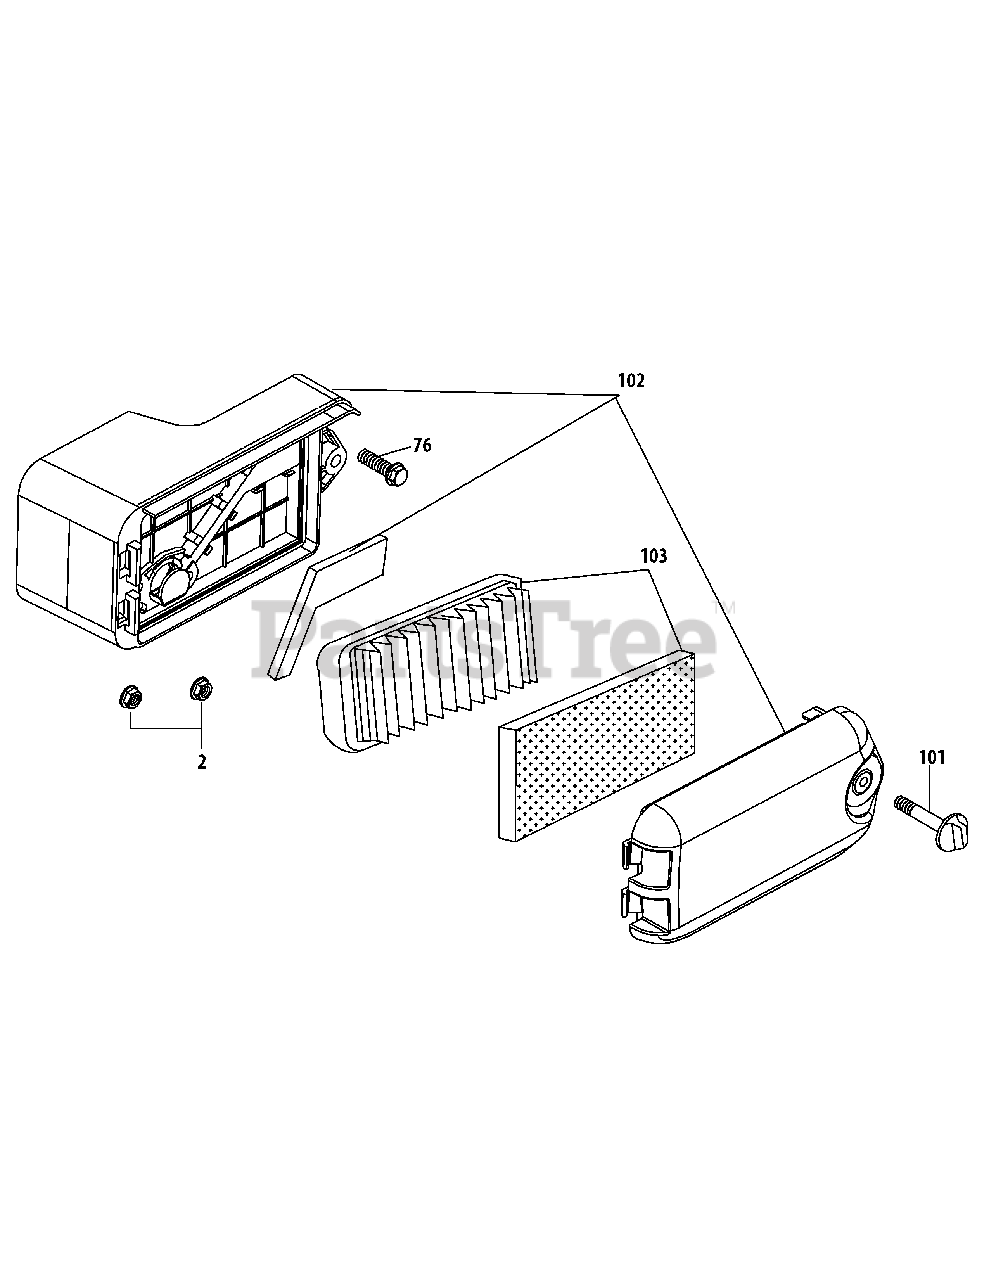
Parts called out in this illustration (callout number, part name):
2	Nut M6
76	Bolt M6×35
101	Air Filter Cover Thumb Screw
102	Air Filter Base
103	Air Filter Element,Sponge
